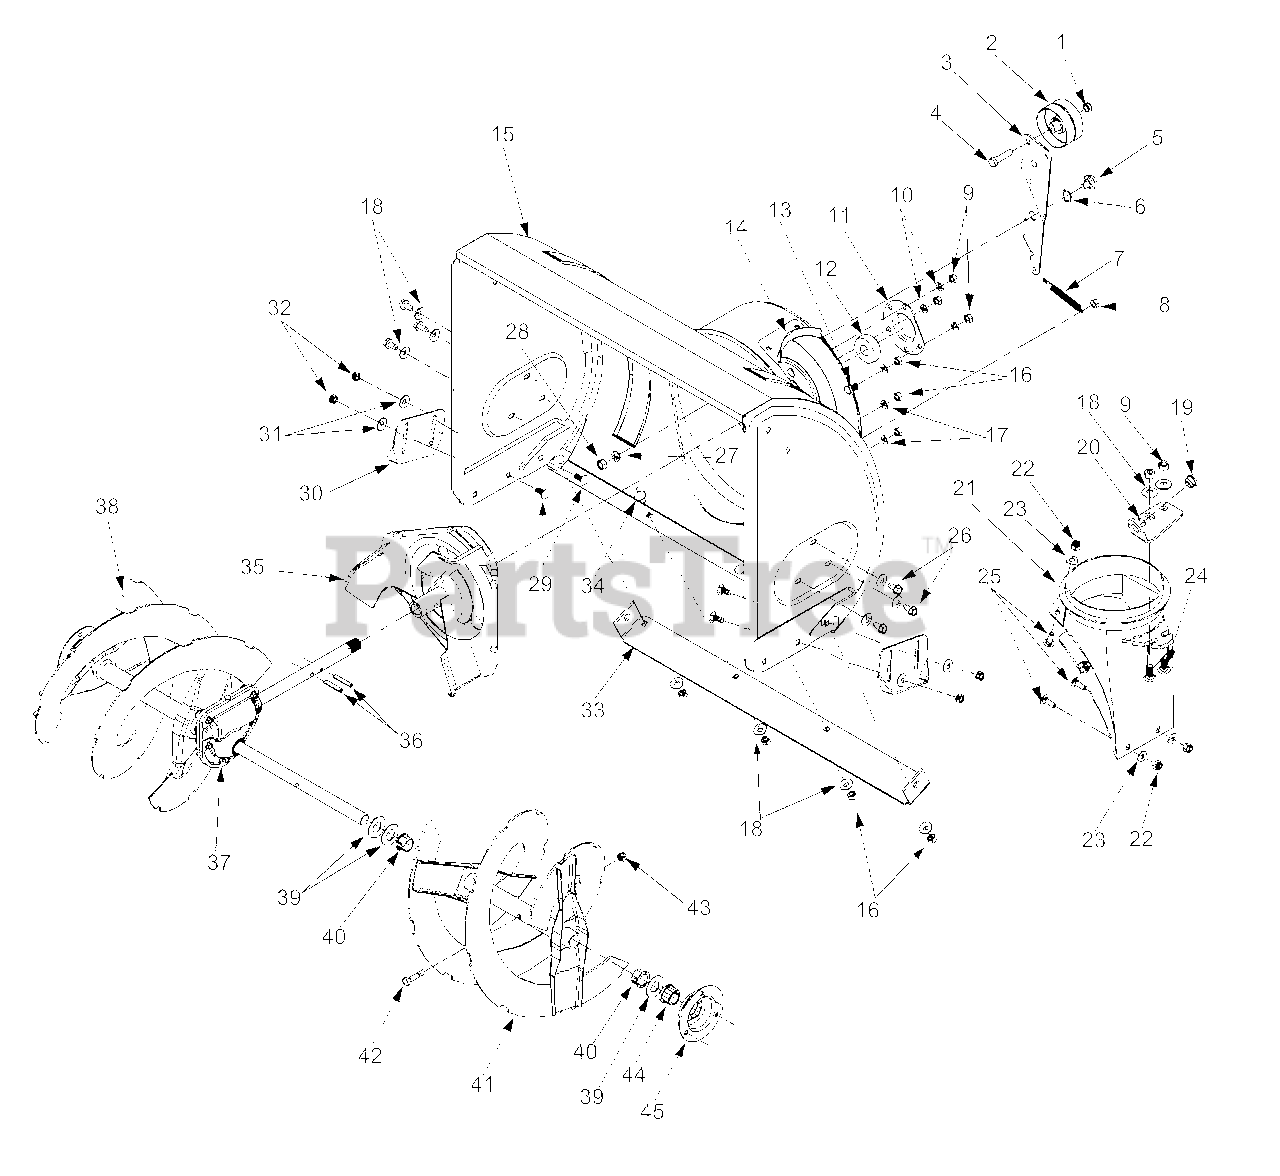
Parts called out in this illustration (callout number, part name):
1	Lock Jam Nut 3/8-24
2	Flat Idler
4	Hex Cap Screw 3/8-24 x 1.50
5	Shoulder Screw
6	Wave Washer
7	Extension Spring
8	Hex Nut 5/16-18
9	Hex Nut 5/16-18
10	Lock Washer 5/16
11	Housing
12	Ball Bearing
13	Carriage Bolt 5/16-18
16	Hex Nut 5/16-18
17	Lock Washer 5/16
18	Bell Washer
19	Bushing
21	Chute Adapter
22	Hex Lock Nut 1/4-20
23	Flat Washer
24	Carriage Bolt
25	Carriage Screw 1/4-20 x .75
26	Hex Washer Screw 5/16-18
27	Lock Washer 3/8
28	Hex Nut 3/8-16
29	Carriage Bolt 5/16-18 x .75
31	Bell Washer
32	Hex Nut 5/16-18
34	Carriage Bolt 5/16-18 x .62
37	22" Gear Assembly
39	Flat Washer
40	Flange Bushing
42	Shear Bolt 5/16-18 x 1.5
43	Lock Nut 5/16-18
44	Hex Flange Bearing
